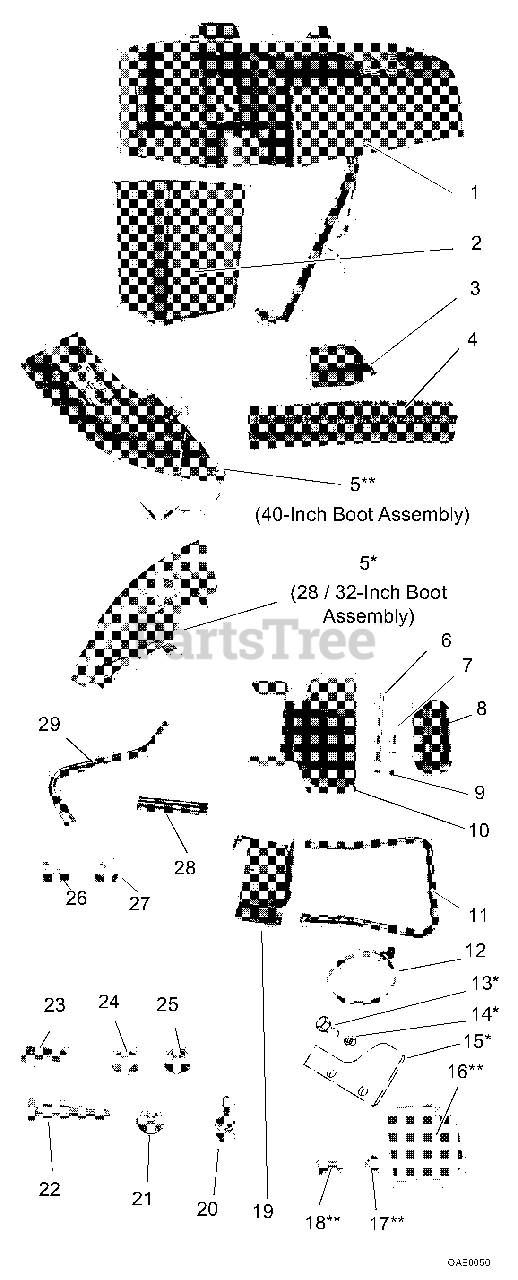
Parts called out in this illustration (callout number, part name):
1	Cover Assembly
2	GRASS BAGGER BASKET
3	BAGGER BOOT - UPPER
4	HOSE 7X38
5	BOOT, 28"&32" DECK BAGGER
5	MOWER BOOT ASSY- 40"
7	@PIN-CTR .25X2.00 YWZC
9	@SCR-TAP .25-20X.50 HWH TR YWZ
10	BRACKET, ROLLER
12	CLAMP, 7" TOOL-LESS HOSE
13	BLT-HEX .31-24X.75 GR8 YWZC
14	NUT-CTRLK .31-24 YWZC
15	VANE
16	VANE
17	NUT-CTRLK .31-24 YWZC
18	BLT-HEX .31-24X.75 GR8 YWZC
19	ASSY,MOUNT BRACKET
20	NUT-NYLK WING .312-18 YWZC
21	@NUT-LK-TOP-FLG .31-18 YWZC
22	@BLT-HEX .31-18X1.50 GR5 YWZC
23	@BLT-HEX .38-16X1.00 GR5 YWZC
24	@WSHR-FL-STL.38X.875X.083 YWZC
25	@NUT-LK-TOP-FLG .38-16 YWZC
26	@BLT-RDHDSQNK .38-16X.75 G5YZ
27	@NUT-SPNLK-FLG .375-16 YWZC
28	BRACE
29	SUPPORT, 28" BAGGER TUBE
